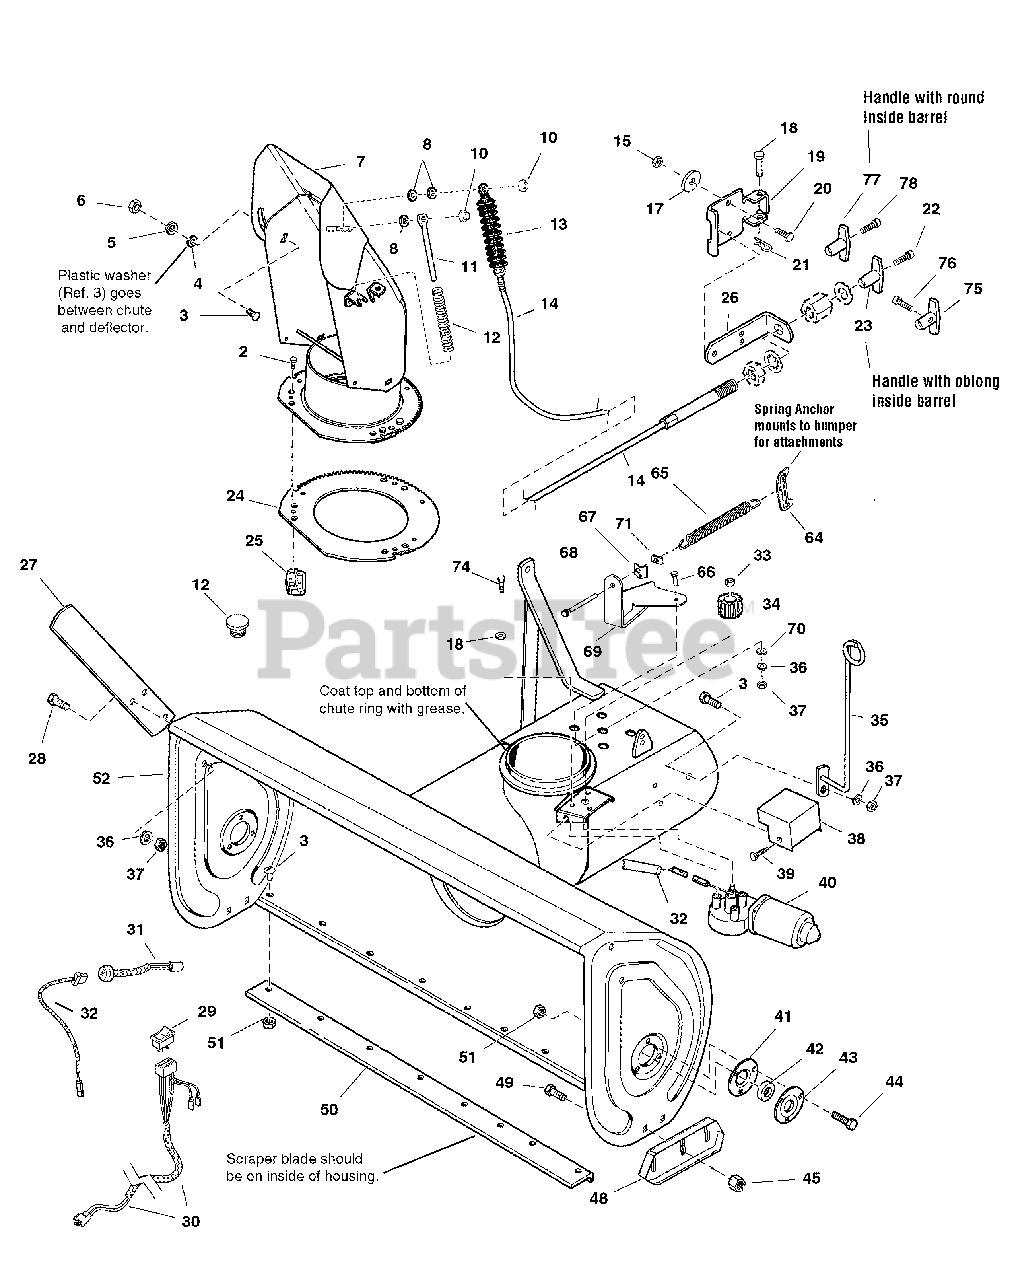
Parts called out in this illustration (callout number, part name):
2	SCREW, Hex Washer Head, Plastite, #10-14 x 5/8
3	CARRIAGE BOLT, 5/16-18 x 3/4
4	WASHER, Nylon
5	WASHER, 5/17, Black
6	NUT, Hex Lock ESNA, 5/16-18
7	CHUTE & DEFLECTOR ASSEMBLY
10	NUT, Push, Black
12	CAP, Plug Black Poly
12	SPRING, Compression
13	BOOT, Water
14	CABLE & KNOB ASSEMBLY (Includes Ref. Nos. 13, 22 & 23)
15	NUT, KEPS, 1/4-20
17	WASHER, 1/4, Black
18	PIN, Flat Head Drilled
19	BRACKET, Mounting
20	CAPSCREW, Hex Head, 1/4-20 x 7/8, Black
21	CLIP, Hair Pin
22	SCREW, Pan Head, #8-32 x 11/16
23	HANDLE, cable
24	GEAR, Chute
25	HOLD DOWN, Chute, Nylon
26	BRACKET, "L"
27	CUTTER, Drift
28	CAPSCREW, Hex Head, 5/16-18 x 3/4, Black
29	SWITCH, Rocker, Chute Rotator
30	HARNESS ASSEMBLY, Spout Rotator, 24" Long
31	HARNESS ASSEMBLY, Power Outlet, 9" Long
32	HARNESS ASSEMBLY, Chute Rotator, 50" Long
33	NUT-KEPS Conical Washer 1/4-20, Black
35	ROD & BAR ASSEMBLY
36	LOCKWASHER, 5/16, Black
37	NUT, Keps Conical Washer, 5/16-18, Black
38	COVER, Pinion
39	CAPSCREW, Hex Washer Head, 1/4-20 x 1/2
40	MOTOR, Electric
41	FLANGE, Bearing
42	BEARING, Cartridge
43	FLANGE, Bearing
44	CAPSCREW, Hex Head, 5/16-18 x 7/8, Black
45	NUT, ESNA Flange, 3/8-16, Black
48	SKID PLATE ASSEMBLY
49	CARRIAGE BOLT, 3/8-16 x 1, Black
50	BLADE, Scraper, 42"
51	NUT, Hex Flange Lock, 5/16, Black
52	HOUSING & IMPELLER ASSEMBLY, 42"
64	SPRING, Anchor
65	SPRING, Extension
66	CAPSCREW, 5/16-18 x 1
67	SPRING, Retainer
68	CAPSCREW 5/16-18 x 4 1/2
69	SPRING, Anchor Assembly
74	CAPSCREW, SEMS GD PT 1/4-20 7/8
76	SCREW, Set, Hex #10-24 x 3/8
77	HANDLE "T"
78	SCREW, Round Head
